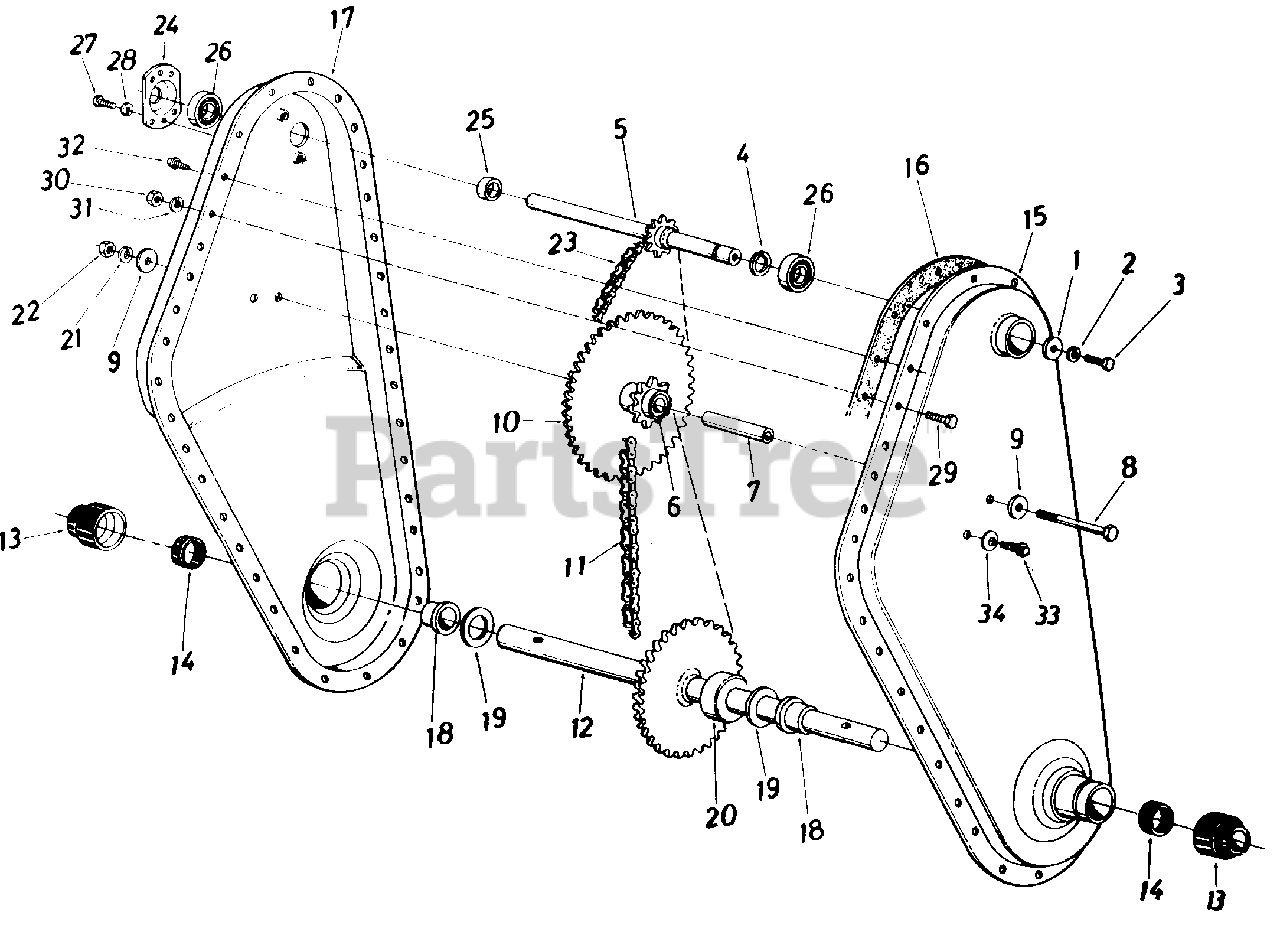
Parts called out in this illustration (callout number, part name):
1	Fl-Wash. 1/4" I.D. x .93" O.D. x . 1 20
2	L-Wash. 1/4" I.D.
3	Hex Bolt 1/4-28 x .62" Lg. w/ Patch
4	External Snap Ring-5/8" Dia.
5	Input Shaft Ass'y.
6	Bearing 5/8" I.D. x 3/4" O.D. x 1.860" Lg.
7	Sprocket Hub Tubing 3/8" I.D. x 5/8" O.D. x 1.90
8	Hex Bolt 3/8-24 x 2.75" Lg.
9	Fl-Wash. 3/8" I.D. x 1.25" O.D. x .10
10	Sprocket Ass'y.
11	#50 Chain 5/8" Pitch x 46 Links Endless
12	Tine Shaft Ass'y.
13	Dust Cup
14	Seal Ring Single Lip, Springless
19	Fl-Thrust Wash. 1.0" I.D. x .03 Thk.
20	Step Spacer
21	L-Wash. 3/8" I.D.
22	Hex Nut 3/8-24 Thd.*
23	#35 Chain 3/8" Pitch x 52 Links Endless
24	Bearing Housing 1.38" I.D.
25	Spacer
26	Ball Bearing .625" I.D. x 1.38" O.D. x .437
27	Hex Wash. SF-Tap Scr. 1/4-20 x .50" Lg.
28	L-Wash. 1/4" I.D.
29	Hex Bolt 5/16-18 x .75" Lg.
30	Hex Nut 5/16-18 Thd.
31	L-Wash. 5/16" I.D.
32	Hex Wash. SF-Tap Scr. 1/4-20 x .50" Lg.
33	Hex Wash. Hd. Tap Scr. 1/4-20 x .38" Lg.
34	Bell-Wash. .265" I.D. x.75 O.D.
